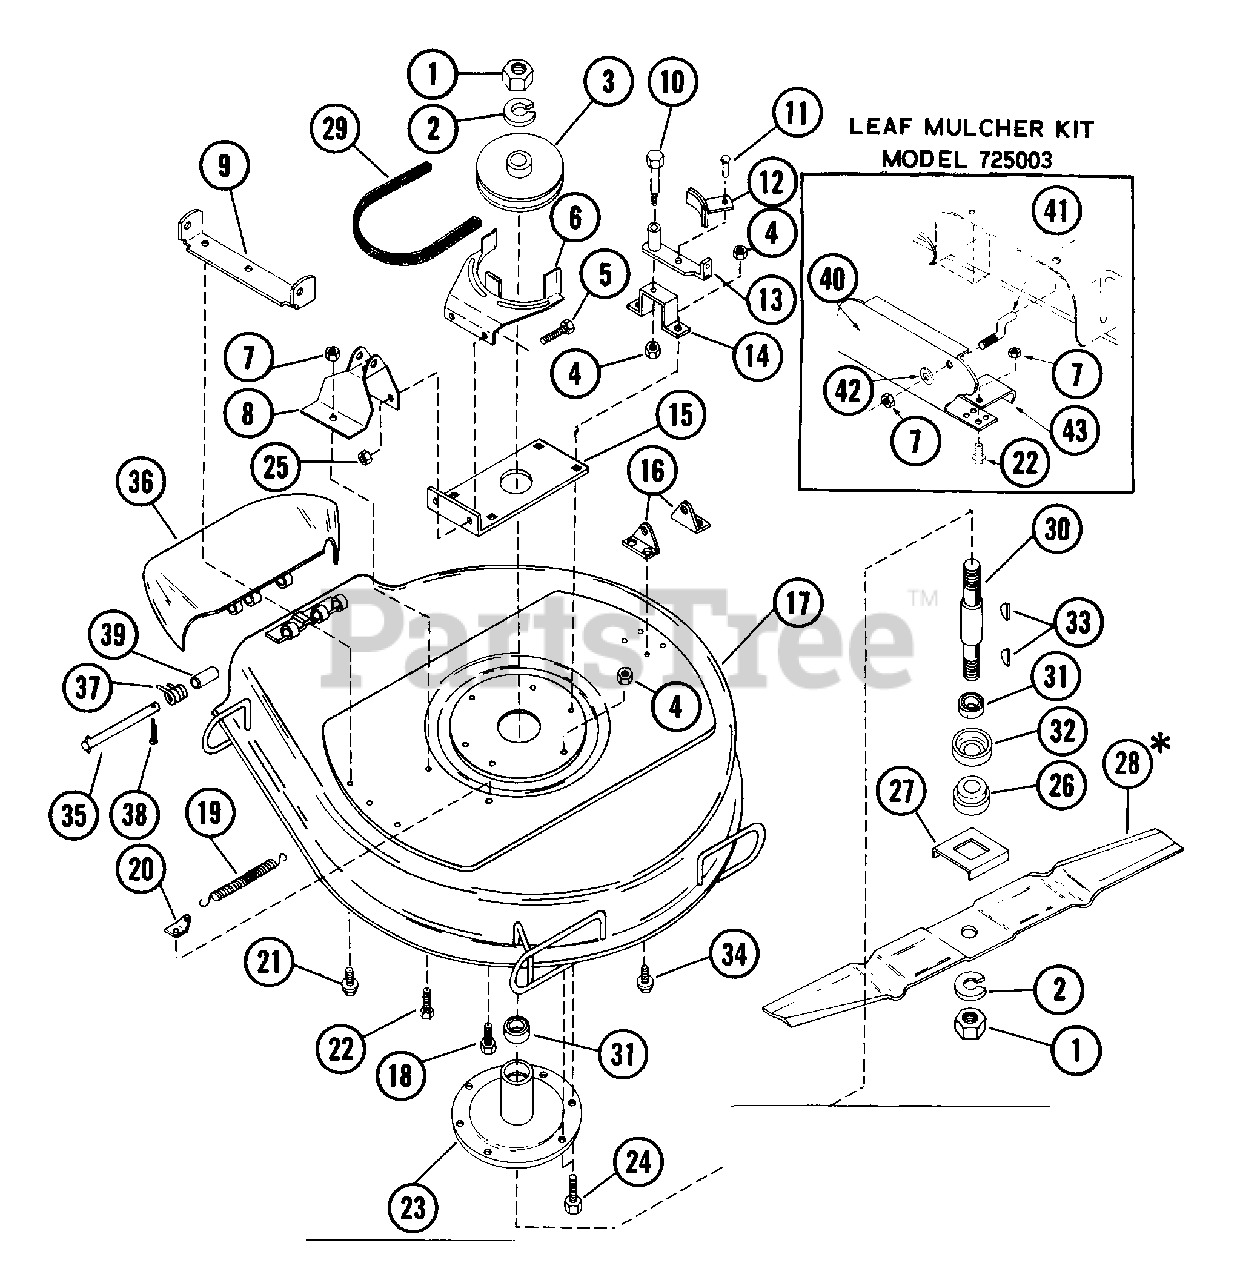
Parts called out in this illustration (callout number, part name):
1	NUT-JAM .75-10 PL
2	WSHR-LK .750X.188 MED PL
3	MOWER SHEAVE
4	NUT-LK-CTR .375-16 GR A PL
5	BLT-SERHFWH .31-18X.75 PL
7	NUT-LK .312-18 GR A PL
8	BRACKET
9	FRONT MOUNTING BRACKET
10	SHOULDER BOLT .50 X 1.75
11	RVT .25X.50 RH ST
12	BLADE BRAKE
14	BLADE BRAKE SUPPORT
16	REAR MOUNTING BRACKET
17	PAN ASSEMBLY
18	BLT-SERHFWH .25-20X.50 PL
19	SG-TENS .072X.51X5.31 WLD 25
20	BRAKE CLIP
21	BLT-SCRHFWH .38-16X.50 PL
22	BLT-HEX .31-18X.50 PL GR2
23	SPINDLE HOUSING
24	BLT-HEX .38-16X1.00 PL
25	NUT-FLG. .312-18 PL
26	RETAINER HUB
27	BLADE TRAY
28	MOWER BLADE
29	V-BELT, 5L-RAW EDGE
30	MOWER SPINDLE
31	BRG-BALL .751X1.78X.61
32	BEARING SLINGER
33	KEY-WDRF .188X.75X.313 SAE 9
34	BLT-SERHFWH .31-18X.50 PL
35	CLEVIS PIN
36	PAN CHUTE EXTENSION
37	SG-TORS .095X.50X 1.0
38	PIN-COTR .09X.75 PL
39	BSHG-SLV .334 X .502 X 1.437
40	LEAF MULCHER KIT-EMPEROR
42	WSHR-FL-STL .38X.875X.083 PL
43	MULCHER BRACKET
